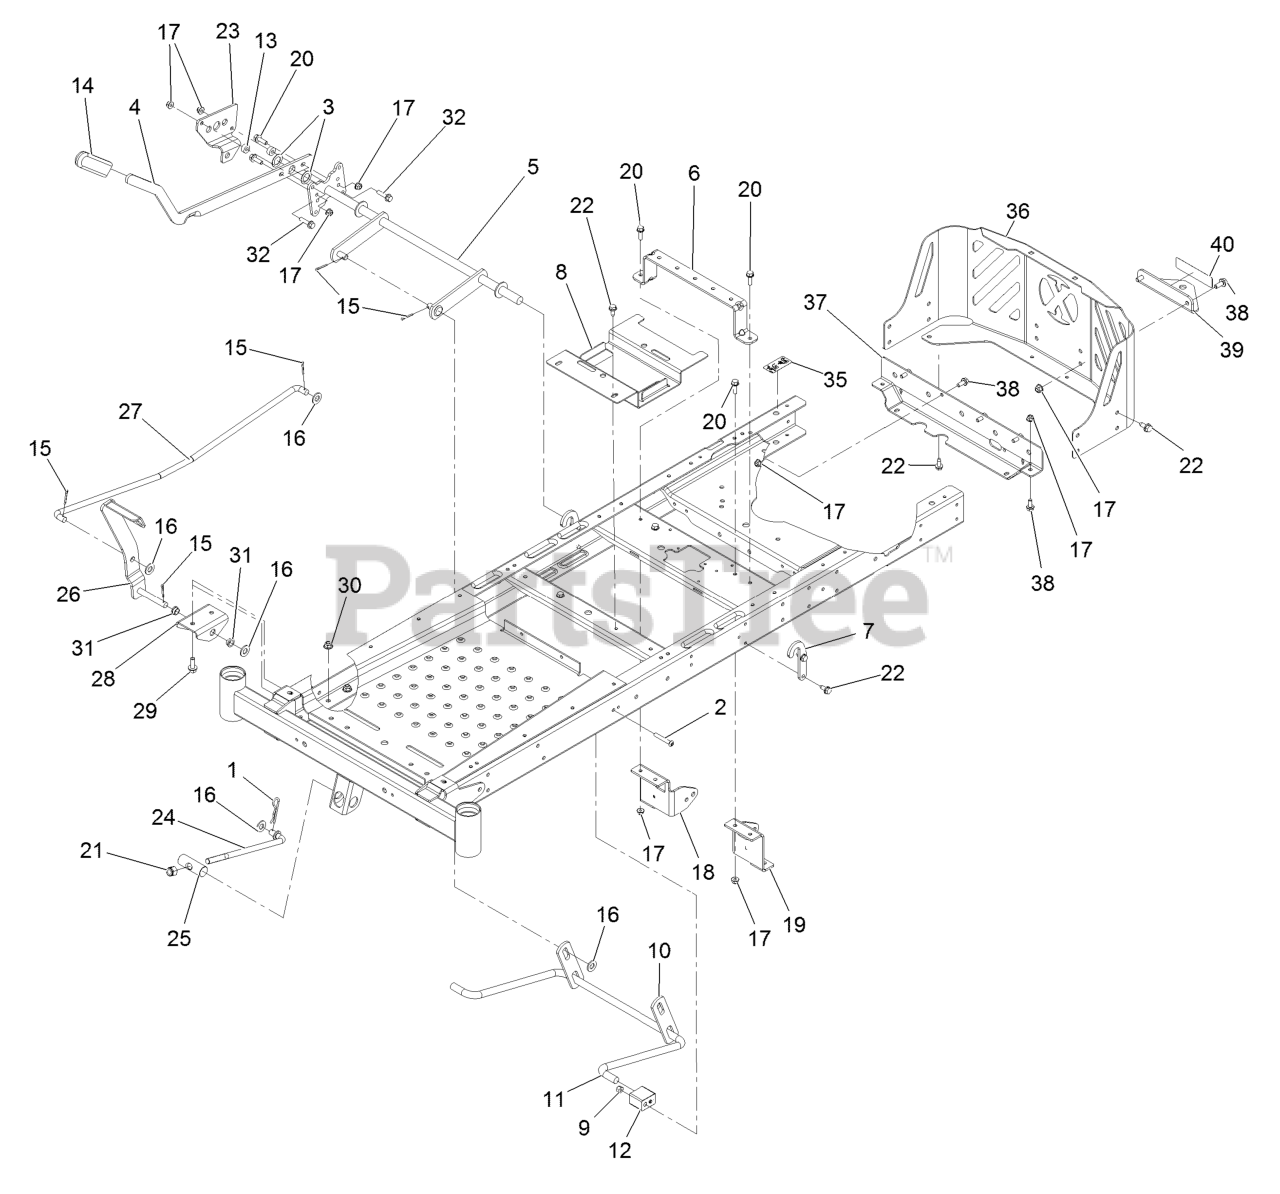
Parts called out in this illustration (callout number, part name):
1	PIN-COTTER
2	SCREW-HSBH
3	WASHER-THRUST
4	LEVER-LIFT
5	LIFT-DECK, NARROW
6	BRACE-SEAT, REAR (NARROW)
7	BRACKET-LIFT
8	BRACKET-BATTERY
9	NUT-LOCK, NI
10	LINK-LIFT
11	ARM-LIFT, REAR
12	BLOCK-PIVOT
14	GRIP-LEVER
15	PIN-COTTER
16	WASHER-FLAT
17	NUT-HF, NI
18	MOUNT-HYDRO, FRONT (RH)
19	MOUNT-HYDRO, FRONT (LH)
20	SCREW-HHF
21	NUT-HEX
22	Screw-HWH 5/16-18 X 3/4 Tf
23	PLATE-FOOTLIFT
24	ROD-MOUNT, DECK
25	PIN-PIVOT
26	PEDAL ASM
27	ROD-FOOTLIFT
28	BRACKET-FOOTLIFT
29	SCREW-HHF 3/8-16 X 1
30	NUT-HF, NI
31	BUSHING-FLANGE
32	SCREW-HHF
35	DECAL-BYPASS
36	GUARD-ENGINE, NARROW
37	CROSSMEMBER-REAR, NARROW
38	SCREW-HHF
39	BRACKET-HITCH
